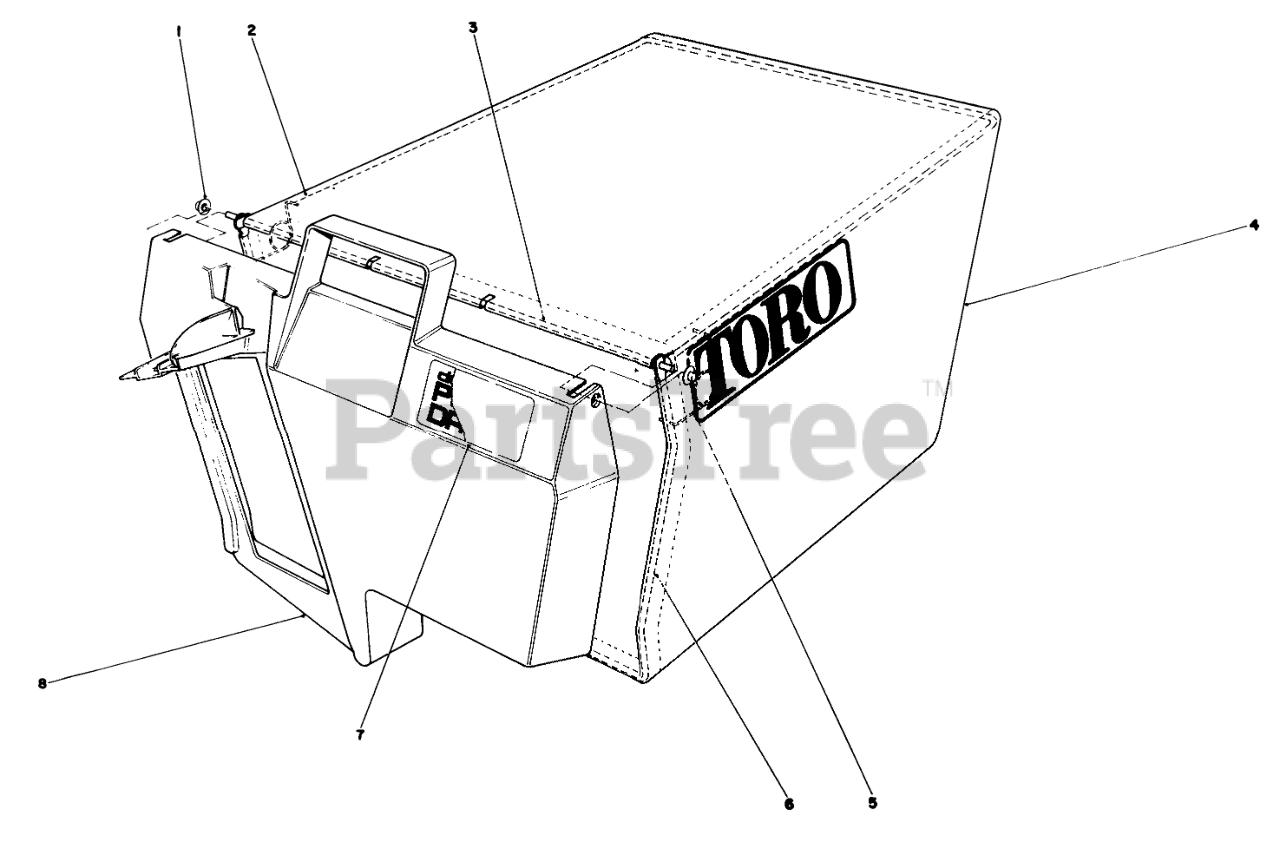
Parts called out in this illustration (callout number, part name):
1	NUT-PUSH
2	FRAME-BAG, UPPER
3	HINGE-DOOR, BAG
4	BAG-GRASS
5	SPRING
6	FRAME-BAG
7	BAG DOOR DECAL
8	DOOR-BAG
